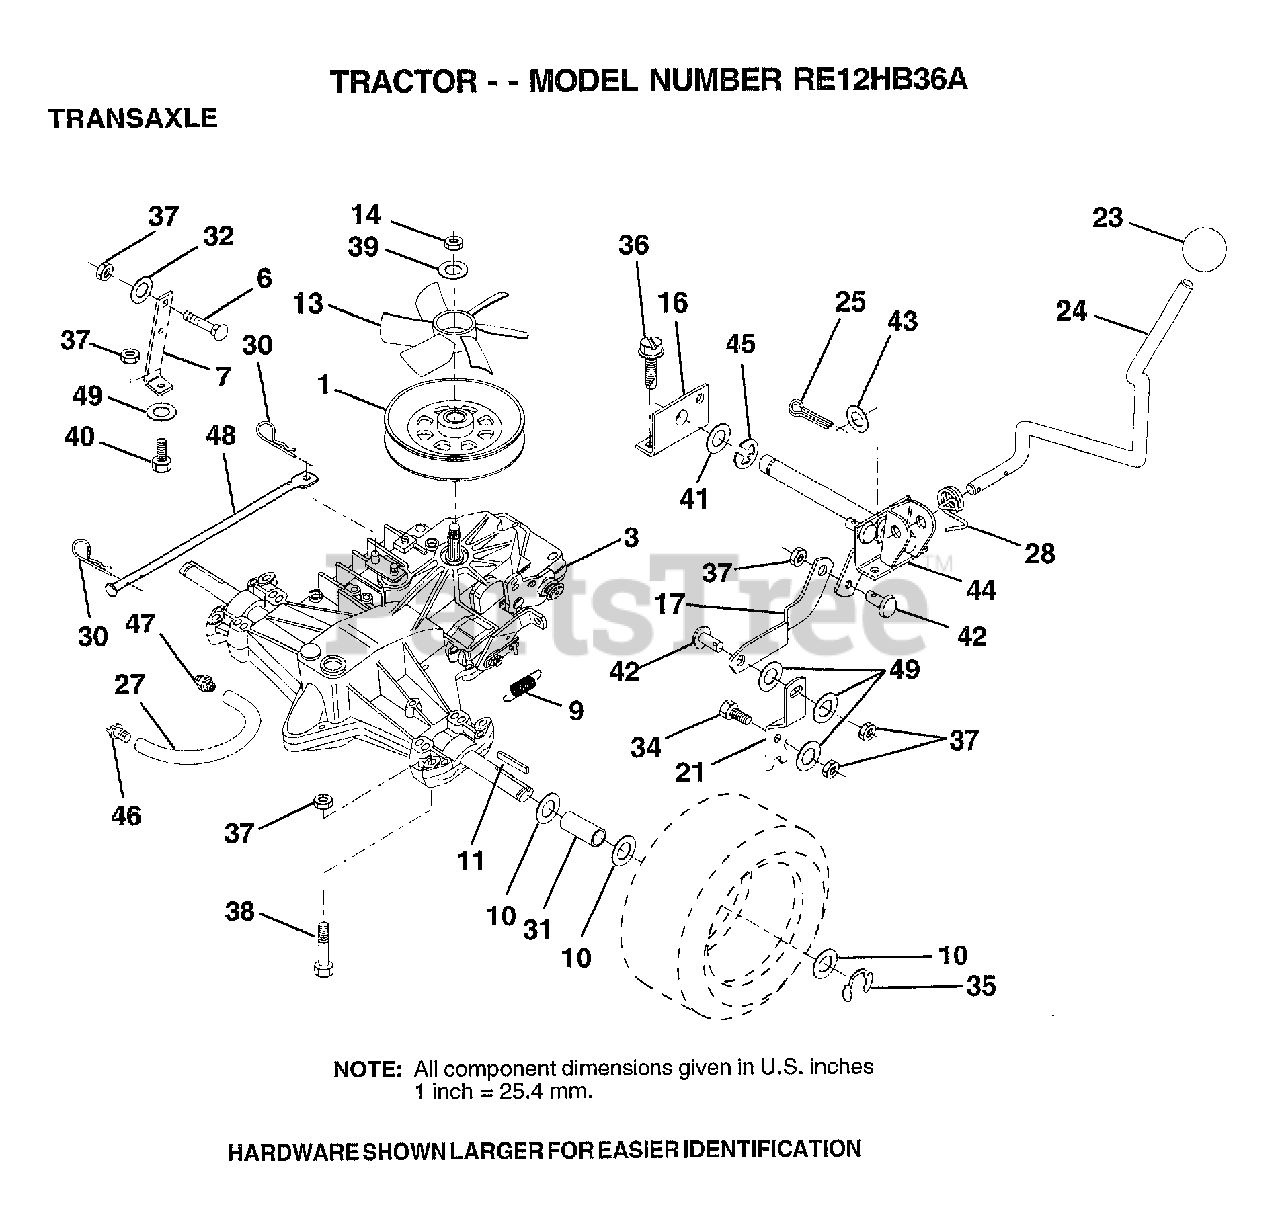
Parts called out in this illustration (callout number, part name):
1	PULLEY.V-GROOVE
6	BOLT
7	STRAP.TORQUE.HYD
9	SPRING.BRAKE.RETU
10	WASHER
11	SQUARE KEY
13	FAN.HYDRO.6FANS
14	"LOCKNUT,1/2-20UNF"
16	SUPPORT.HDLE.SHFT
17	LINK.SHIFT.HYD.LR
21	LEVER.SHIFT.TRANS
23	KNOB T (1/2-HOLE)
24	ROD.SHIFTER.HYD.
25	PIN COTTER 1/8
27	"LINE FUEL HYD 4"""
28	SPRING.TORSION.LR
30	RETAINER M
31	SPACER SPLIT
32	WASHER
35	E-RING LT
36	SCREW
37	NUT
38	BOLT.HEX.FLGHD
39	WASHER
40	BOLT.HEX.5/16-1.5
41	WASHER
42	PIN.PIVOT.SHIFT.
43	WASHER
44	SHAFT.PIVOT.LR.
48	ACTUATOR.BYPASS
49	WASHER M
